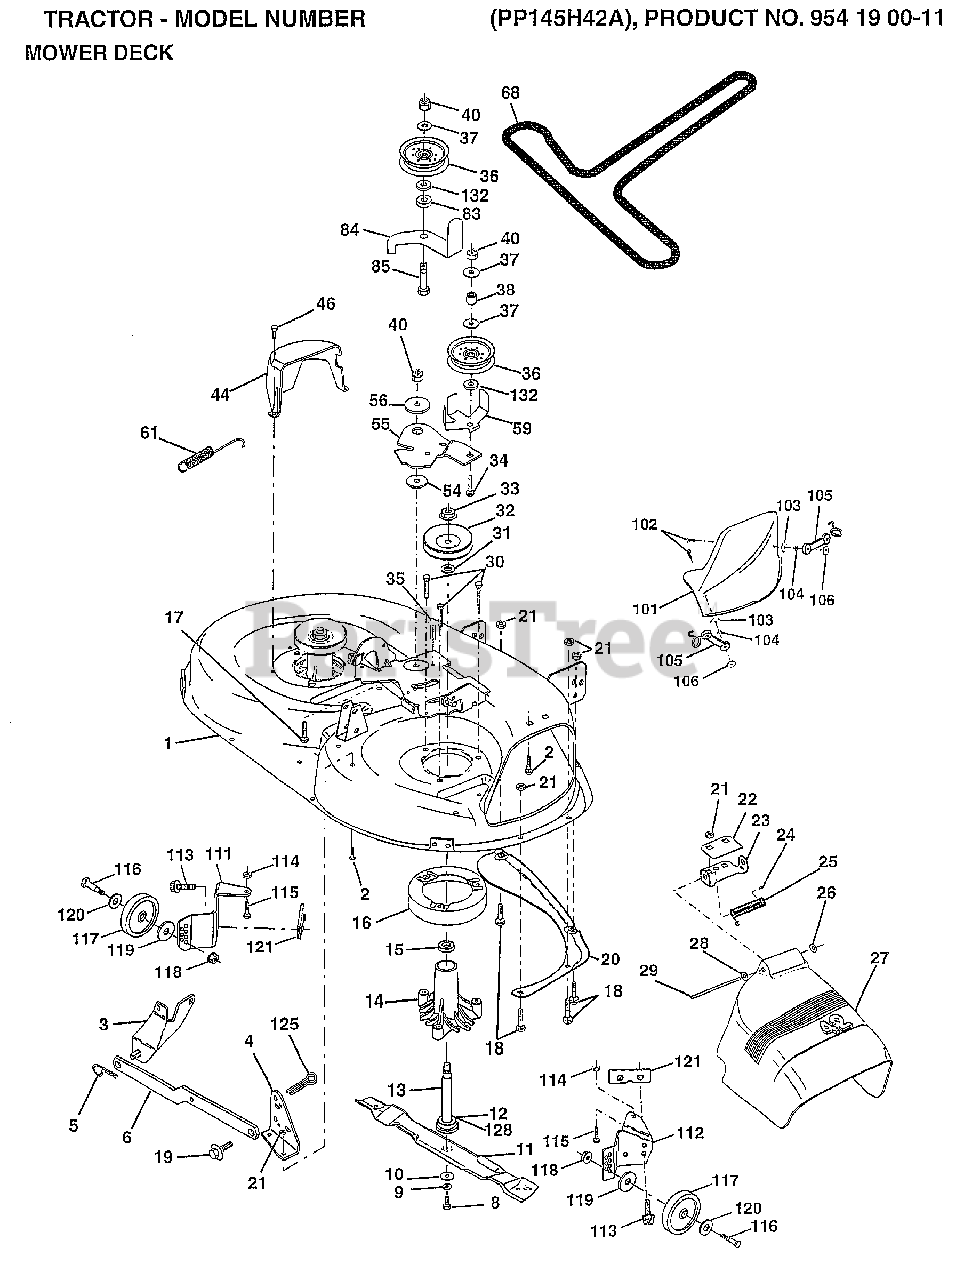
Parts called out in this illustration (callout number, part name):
1	DECK.WELD.42.
2	BOLT
3	BRKT ASM SWAY BAR
4	BRKT DECK SW BAR
8	BLADE BOLT
10	WASHER.HARD.BLADE
11	"BLADE.42"" MULCHER"
12	BEARING.BALL
14	HSG ASM MANDREL
15	BEARING
16	STRIPPER RND MWR
17	BOLT CARRIAGE
18	BOLT
19	BOLT SHD 5/16-18
22	STIFFENER BRKT
23	DEFLECTOR BRKT
24	CAP-SLEEVE LT
25	SPRING TORSION
26	NUT PUSH M
27	DEFLECTOR.SHIELD
28	WASHER
29	HINGE ROD
31	WASHER
32	PULLEY.MANDREL.42
34	BOLT
35	XMAS TREE FASTNER
36	FLAT IDLER PULLEY
37	WASHER
44	GUARD MAND LH BLK
46	SCREW.1/4-20X5/8
54	HARDENED WASHER
56	SPACER RETAINER
59	GUARD IDLER TUV
61	SPRING.EXTENSION
68	BELT.V.T-PATH
83	WASHER
84	"KEEPER-BELT,FIXED"
85	BOLT RDHD 3/8-16
101	"COVER.MULCH.42"""
102	SCREW
103	WASHER #10
104	LOCKWASHER
106	WELDNUT
111	BRACKET.GWHL.LH.
112	BRACKET.GWHL.RH.
113	SCREW
116	BOLT M
117	WHEEL.GAGE.BLK.PL
118	LOCKNUT
119	WASHER
120	WASHER
121	BRACKET.EXTRD.GWL
125	COTTER PIN
128	WASHER.FELT.
132	WASHER GT
